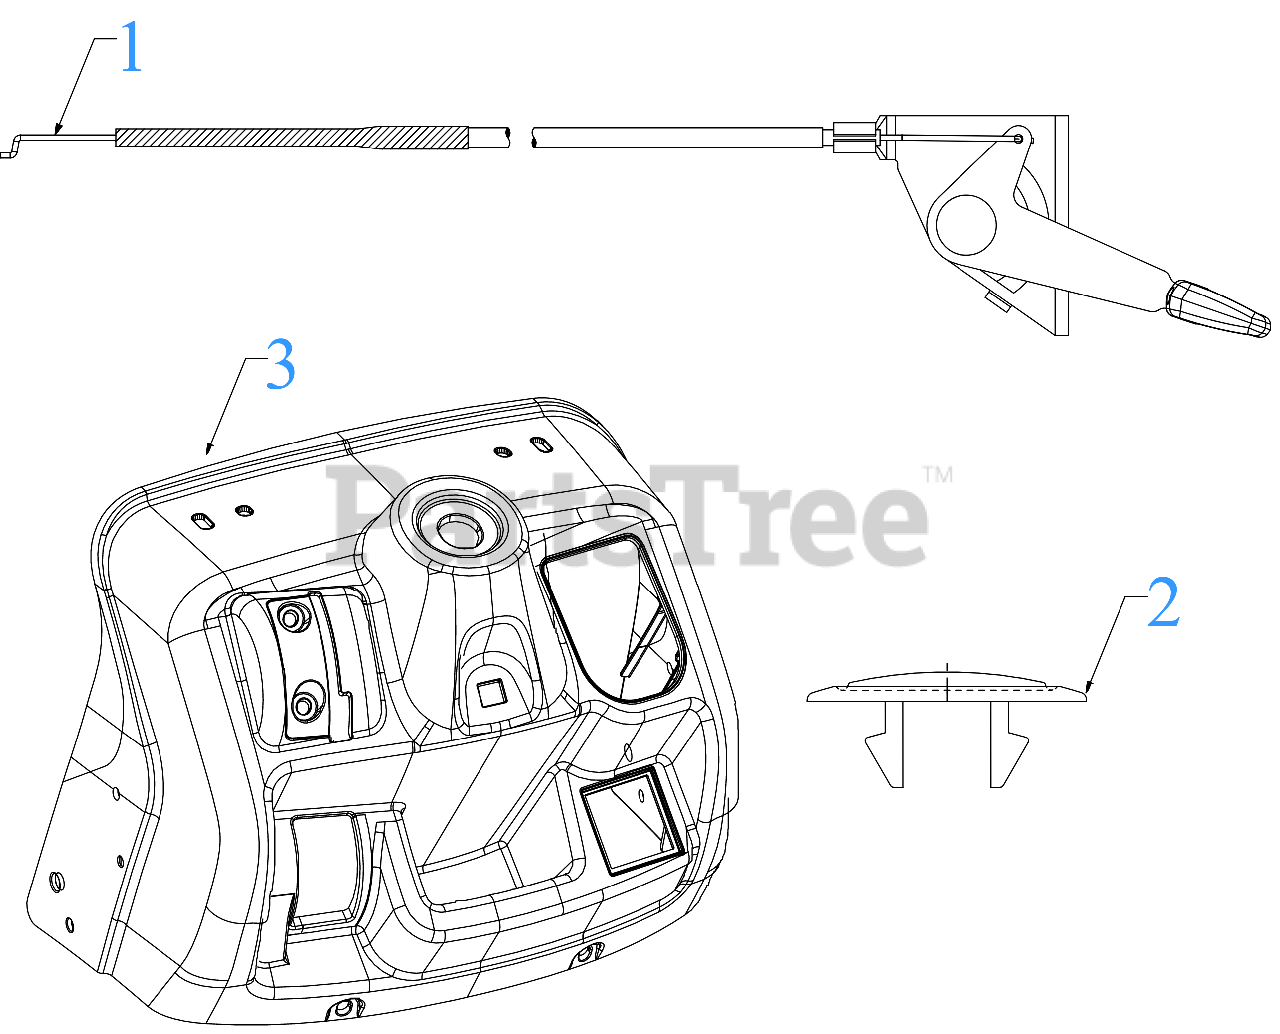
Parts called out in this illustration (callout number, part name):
1	THROTTLE CABLE 31" x 1.1
2	CHOKE PLUG
3	UPPER DASH
